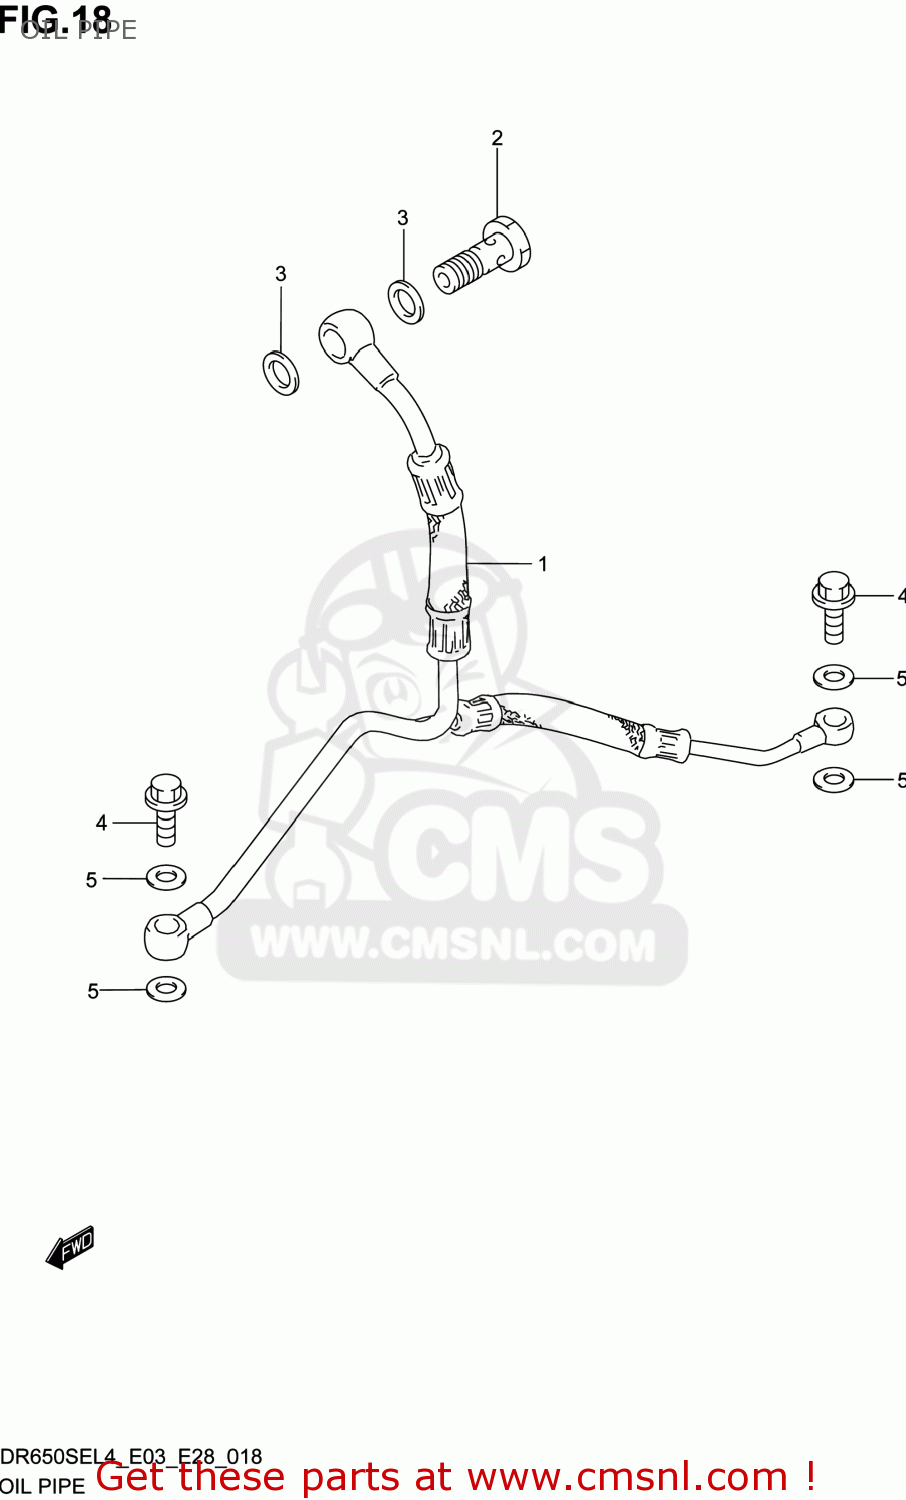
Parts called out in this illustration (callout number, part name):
1	PIPE,T/M & CSHAFT OIL
2	BOLT UNION
3	GASKET(12X17X1) (NAS)
4	BOLT UNION
5	GASKET(10.1X16X1) (NAS)
